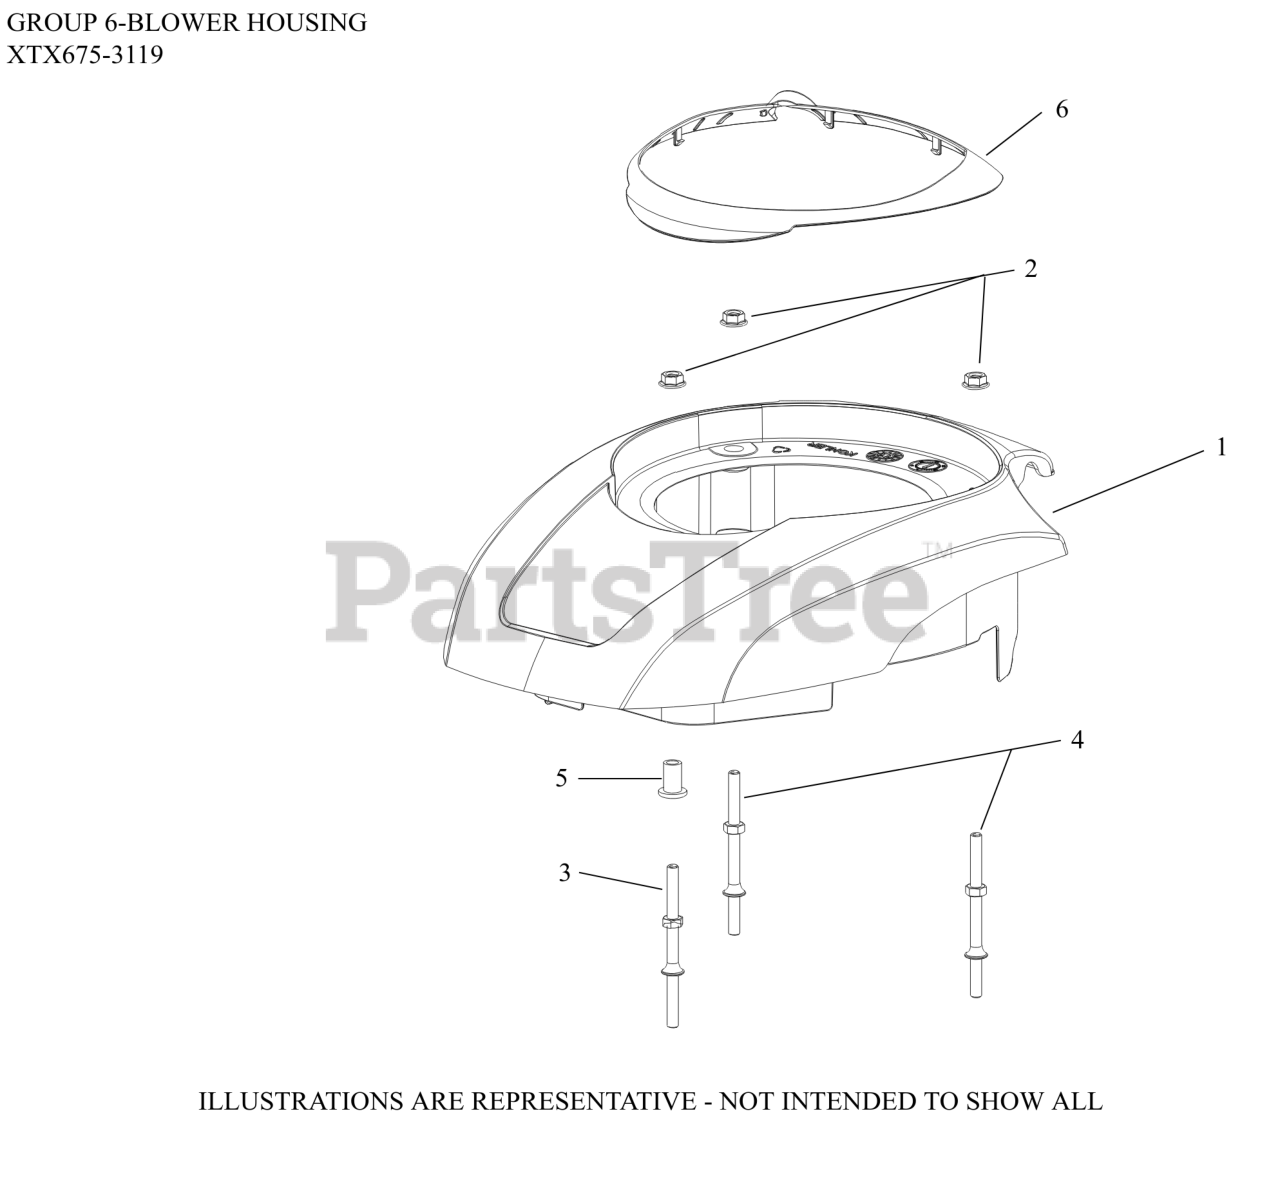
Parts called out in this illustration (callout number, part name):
1	COVER, ENGINE
2	NUT, HEX FLANGE (M6) - USE 14 100 16-S
3	STUD-USE 14 072 25-S
4	STUD-USE 14 072 26-S
6	INSERT, TRIM PIECE
